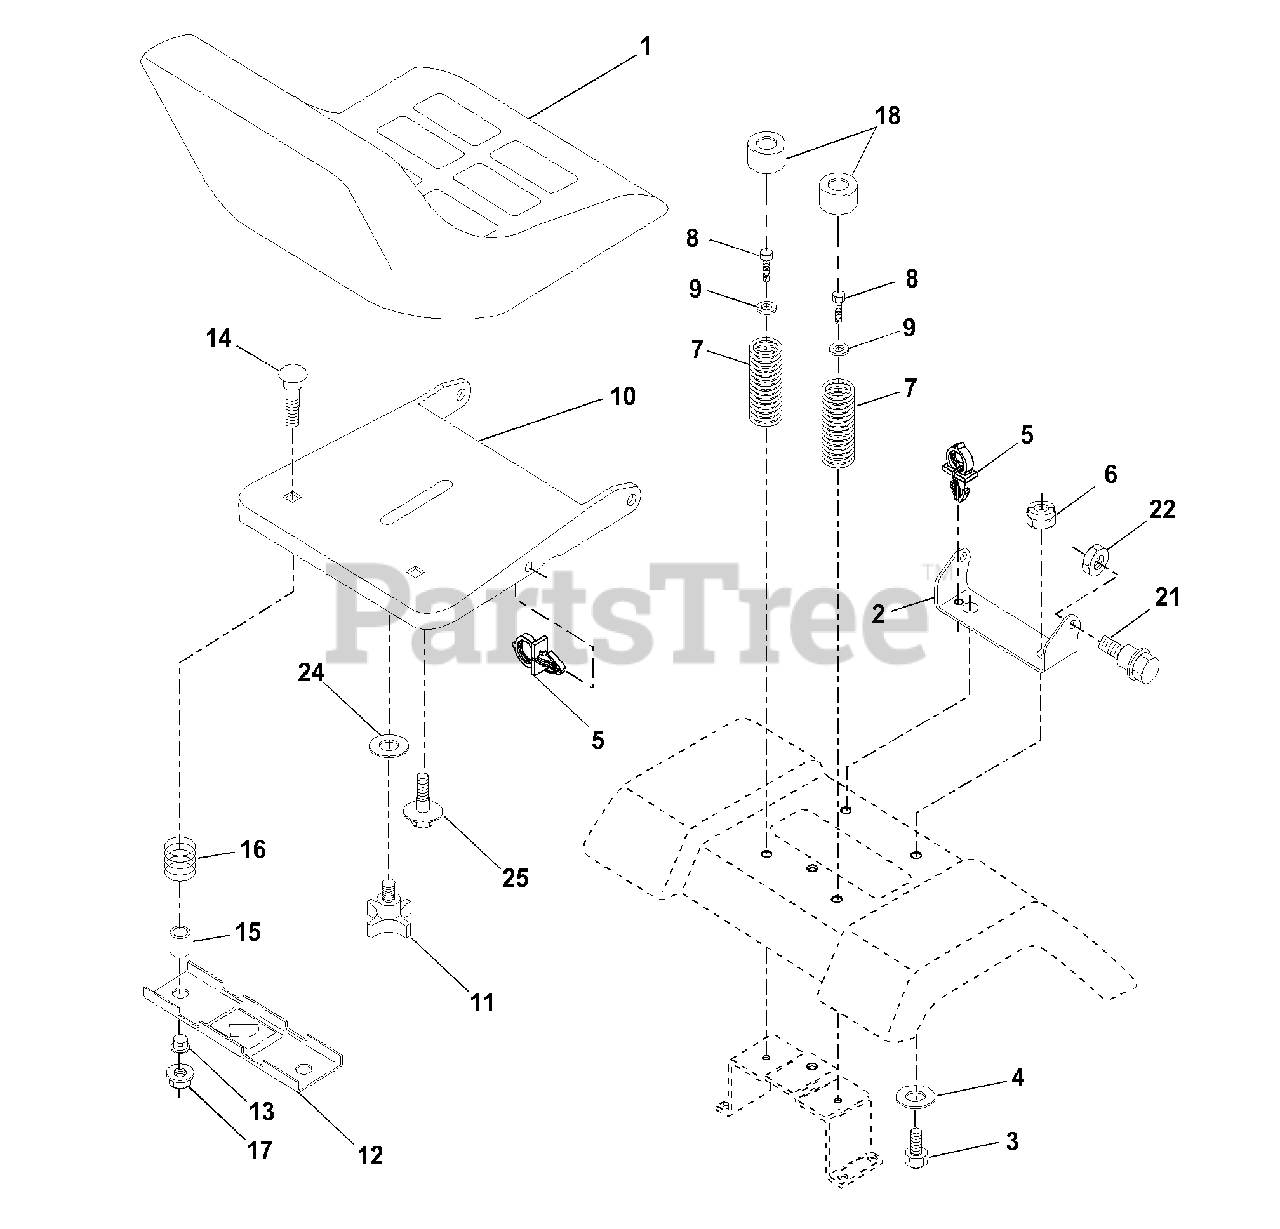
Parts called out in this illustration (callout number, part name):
1	Seat V250 Blk/blk Std
2	Bracket Pivot Seat 8 720
3	Bolt Fin Hex 3/8-16unc X 1
4	Washer 13/32 X 1 X 10 Ga
5	Clip Push-In
6	Nut Hex w/Ins. 3/8-16 Unc
7	Spring Seat Cprsn 2 250 Blk Zi
8	Screw Thdrol 3/8-16 X 1 Ty-tt
9	Washer 13/32 X 1 X 14 Ga.
10	Pan Seat
11	Knob seat 1/2-13 Unc
12	Bracket Mounting Switch
13	Bushing Snap Blk Nyl 50 Id
14	Bolt Rdhd Sht Nk 1/4-20x1-3/8
15	Spacer Split 28x 96 Yel Zinc
16	Spring Cprsn 1 27 Blk Pnt
17	Nut Lock 1/4 Lge Flg Gr 5 Zinc
18	Cap Spring Seat
21	Bolt Shoulder 5/16-18 Unc Blkz
22	Nut Hex Lock W/Ins 5/16-18
24	Washer 17/32 X 1-3/16 X 12 Ga.
25	Bolt Shoulder 5/16-18 X 62
